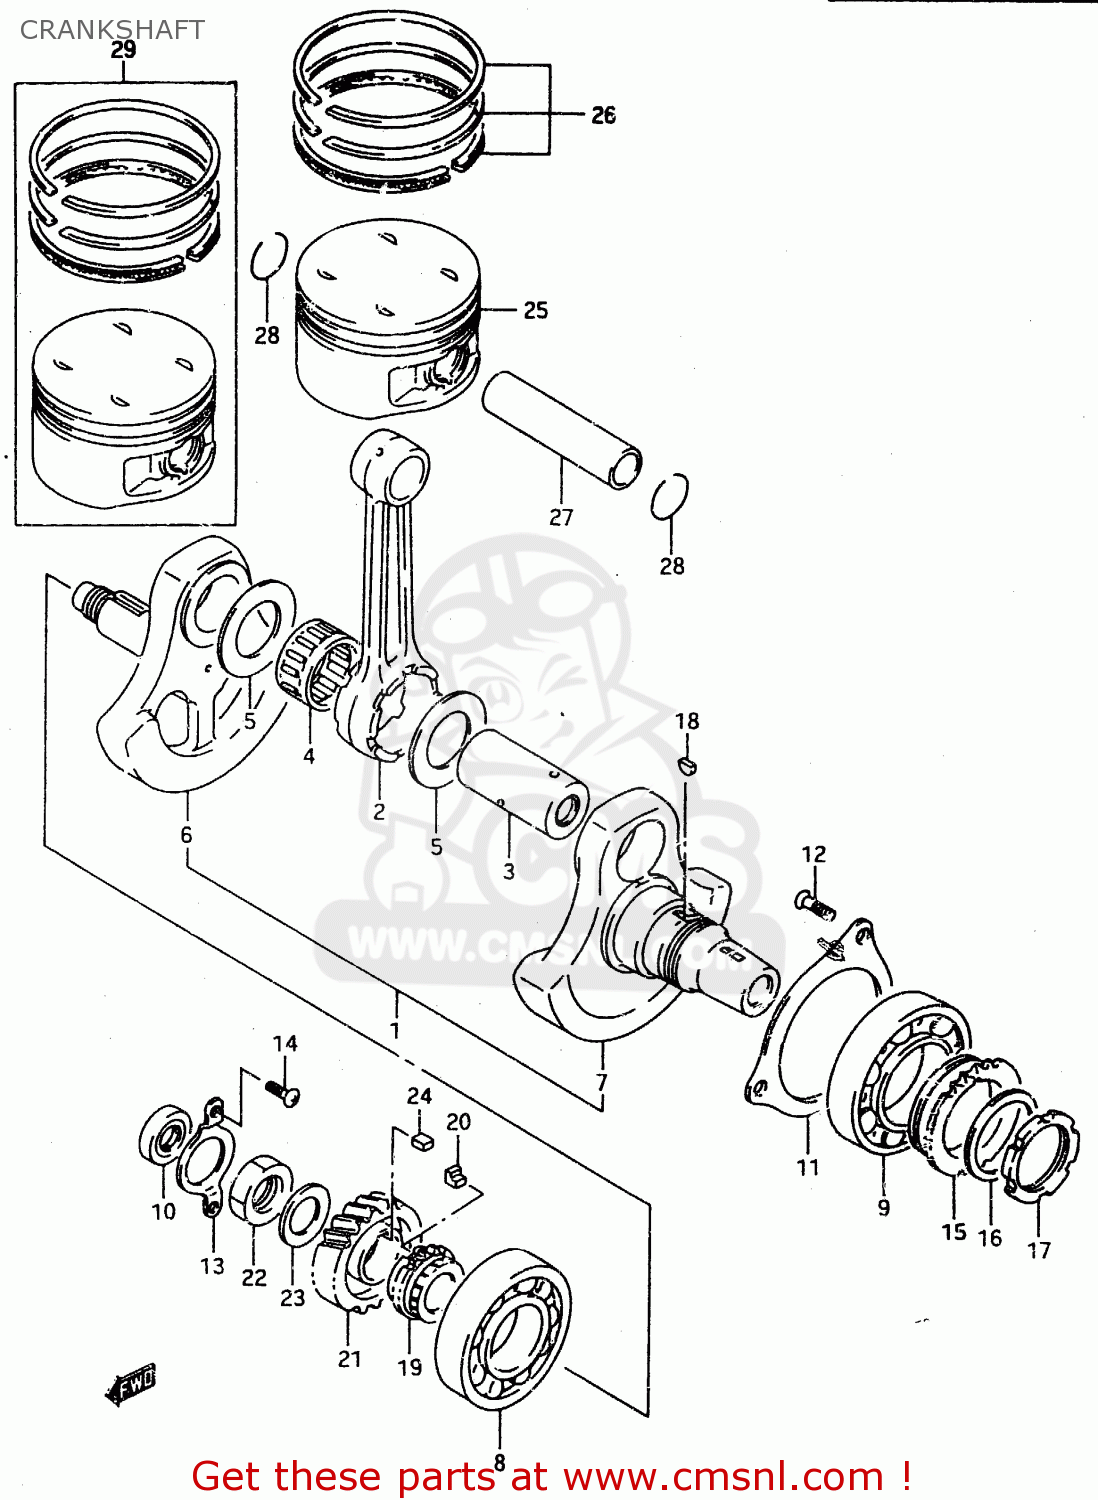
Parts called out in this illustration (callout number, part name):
1	CRANKSHAFT ASSEMBLY
2	ROD,CONNECTING
3	PIN,CRANK
4	BEARING
5	WASHER(35X55X1)
6	CRANKSHAFT,R
7	CRANKSHAFT,L
8	BEARING(35X80X21)
9	BEARING
10	SEAL,OIL(16X30X6)
11	RETAINER,CRANKSHAFT BEARING,L
12	SCREW ,6X16
13	RETAINER,CRANKSHAFT BEARING,R
14	SCREW
15	SPROCKET,BALANCER DRIVE
16	WASHER
17	NUT,BAL DRIVE SPRKT
18	KEY
19	SPROCKET,CAM CHAIN DRIVE
20	KEY,SPROCKET
21	GEAR,PRIMARY DRIVE
22	NUT (20MM)
23	WASHER
24	KEY
25	PISTON
26	RING SET,PISTON
27	PIN,PISTON
28	CIRCLIP
29	PISTON SET (OS:0.5)
